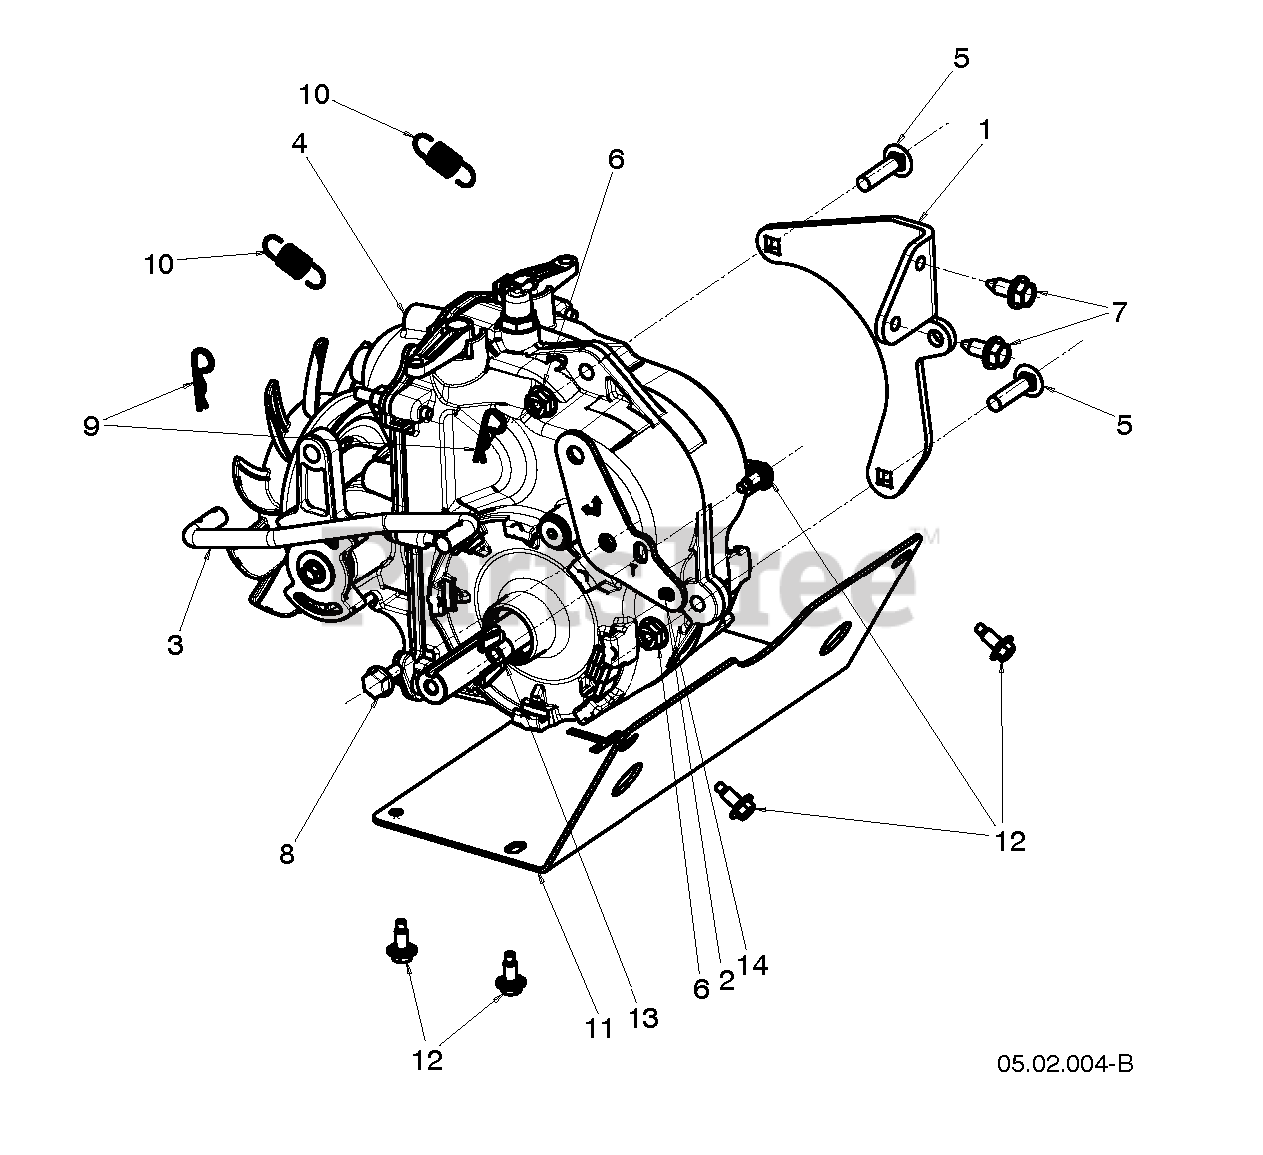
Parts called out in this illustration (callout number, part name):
1	MOUNT TRANSMISSION RAW
2	Bell Cranks
4	TRANSMISSION HYDRAULIC POWER S
5	BOLT.CARRIAGE.5/16-18
6	NUT.LOCK.5/16-18
7	BOLT.HEX.HD.WASHER.5/16-18X.75
8	BOLT SHOULDER 3/8-20 X.25
9	SPRING RETAINER
10	SPRING IDLER RETURN
11	COVER BOTTOM FRAME TRACK RAW
12	HEX.WASHER.HEAD 1/4-20 X .65
14	WASHER
